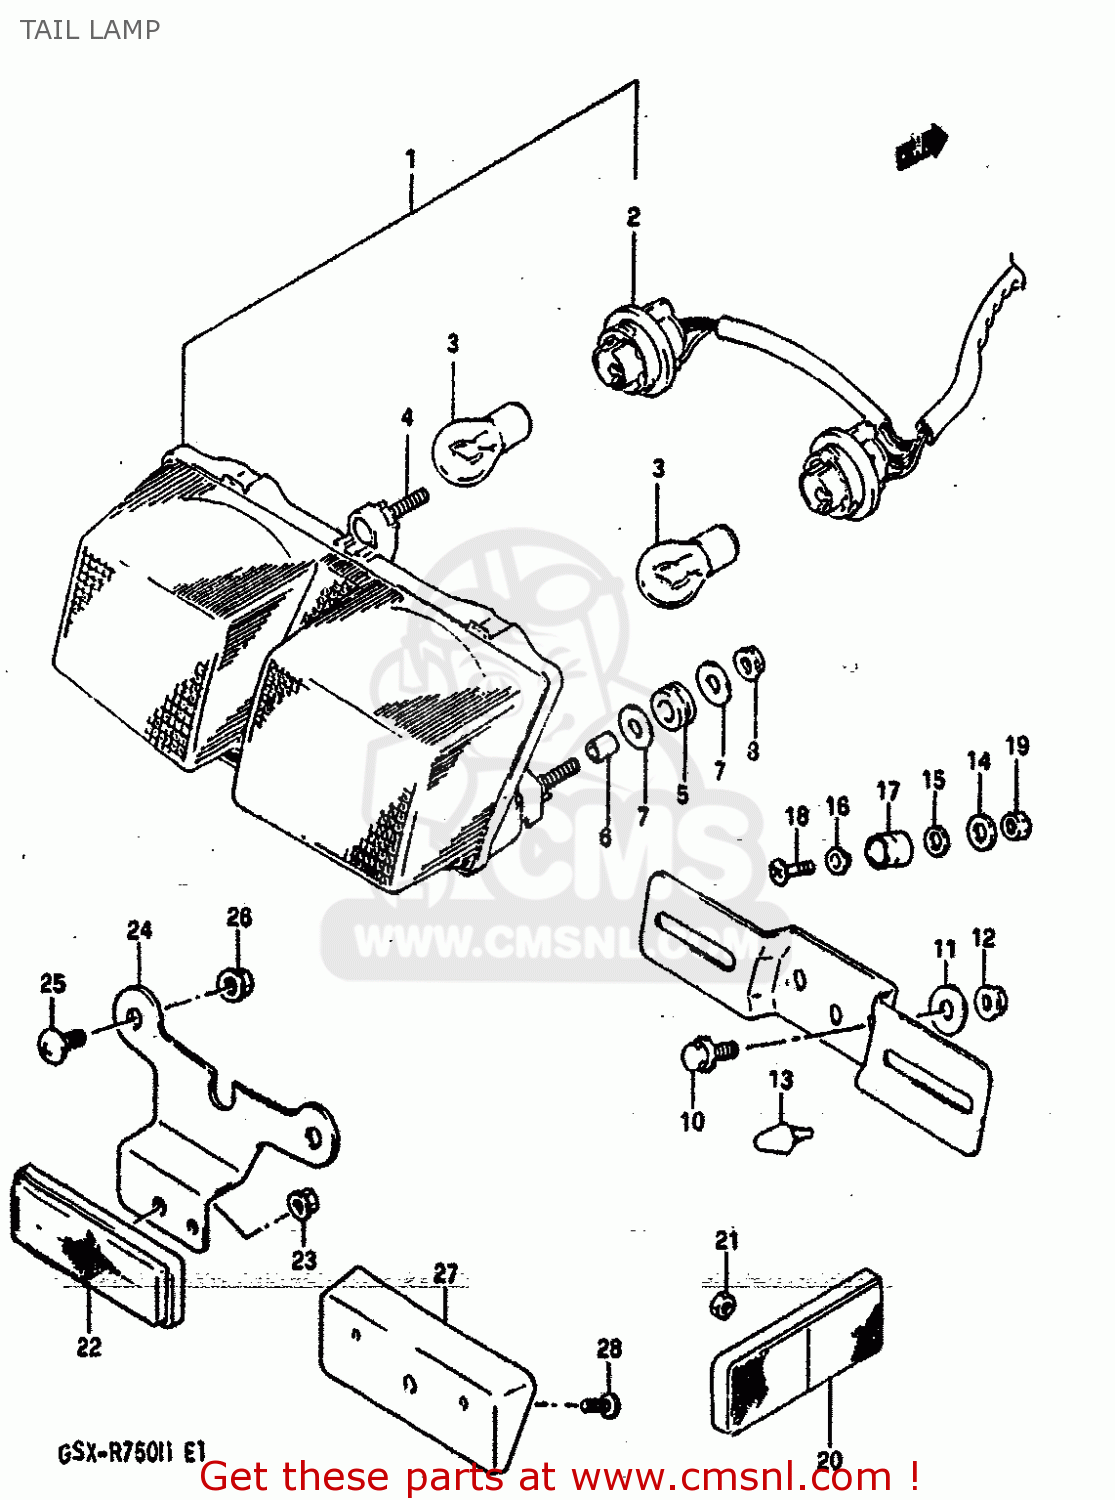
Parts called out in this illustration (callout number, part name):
1	LAMP ,RR COMBI
2	SOCKET ASSEMBLY
3	BULB(12V21/5W)
4	BOLT 6X30
5	CUSHION
6	SPACER (6.1X8X9.5)
7	WASHER(6.5X18X1)
8	NUT
9	BRACKET,LICENSE PLATE
10	BOLT
11	WASHER,COVER,FRONT
12	NUT
13	CUSHION
14	WASHER
15	WASHER
16	WASHER
17	CUSHION
18	SCREW
19	NUT
20	REFLEX REFLECTOR,FR SIDE
21	NUT 5MM
22	REFLECTOR ASSEMBLY,REAR
23	NUT 5MM
24	BRACKET,RR RR
25	SCREW 6X12
26	NUT
27	SPACER,RR RR
28	SCREW
